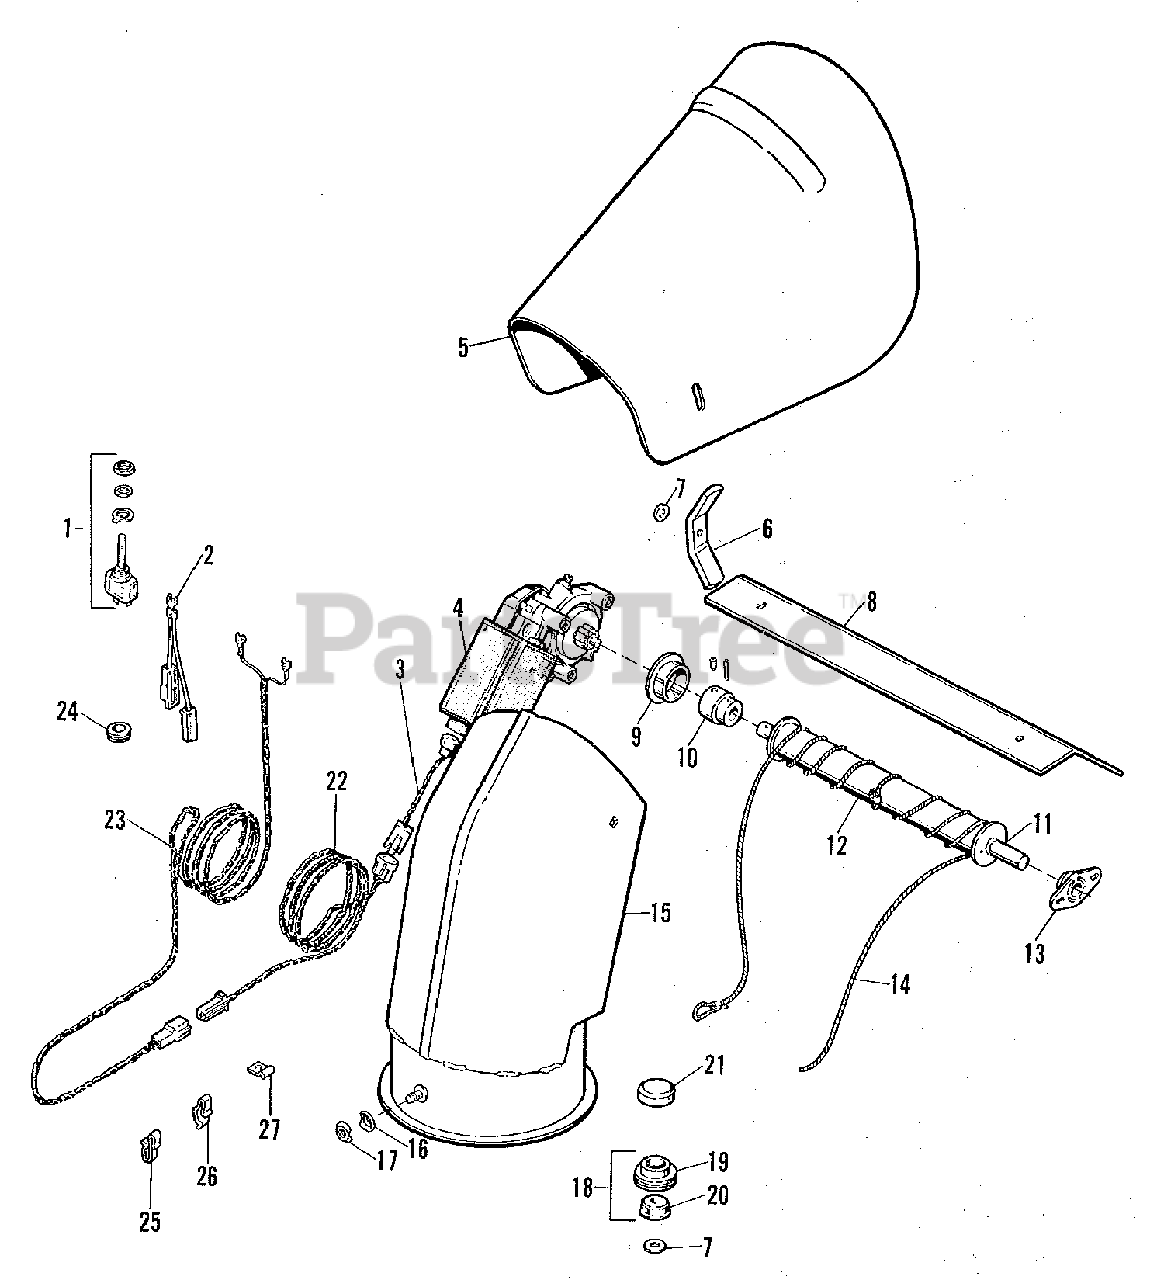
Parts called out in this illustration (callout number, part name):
1	SWITCH, Spout Control
2	WIRE, Chute
3	HARNESS, Adapter
4	MOTOR, Spout Control
4	CAPSCREW, 1/4NC x 3/4
4	WASHER, Plain, 5/16 x 3/4 x 16 Ga.
4	LOCKWASHER, 1/4
5	EXTENSION, Spout
6	BOLT, Carriage, 3/8NC x 3/4
6	WASHER, Lock, Dished, 3/8
8	COVER, Chute Control
8	SCREW, Taptite, 1/4NC x 3/8
9	BEARING, Flanged
10	SETSCREW, Hex Socket Head, No. 10NC x 3/8
10	PIN, Spring, 5/32 x 1
11	TUBE ASSEMBLY, Spout Control
12	SCREW, Taptite, 1/4NC x 3/8
12	WASHER, Plain, 5/16 x 3/4 x 16 Ga.
13	SCREW, Taptite, 1/4NC x 3/8
14	CABLE ASSEMBLY
15	SPOUT ASSEMBLY
15	WASHER, Plain, 5/16 x 3/4 x 16 Ga.
15	NUT, Lock, 5/16NC
16	WASHER, Cup
17	WASHER, Cup
18	BEARING ASSEMBLY, Pulley
18	PULLEY & BEARING ASSEMBLY
19	CAPSCREW, 3/8NC x 1
19	LOCKWASHER, 3/8
20	RING, Retaining
22	HARNESS ASSEMBLY, Motor
23	HARNESS ASSEMBLY, Switch
24	GROMMET, Rubber
25	CLIP, Cable
26	CLIP, Cable
27	CLIP, Cable
27	SCREW, Taptite, 1/4NC x 3/8
